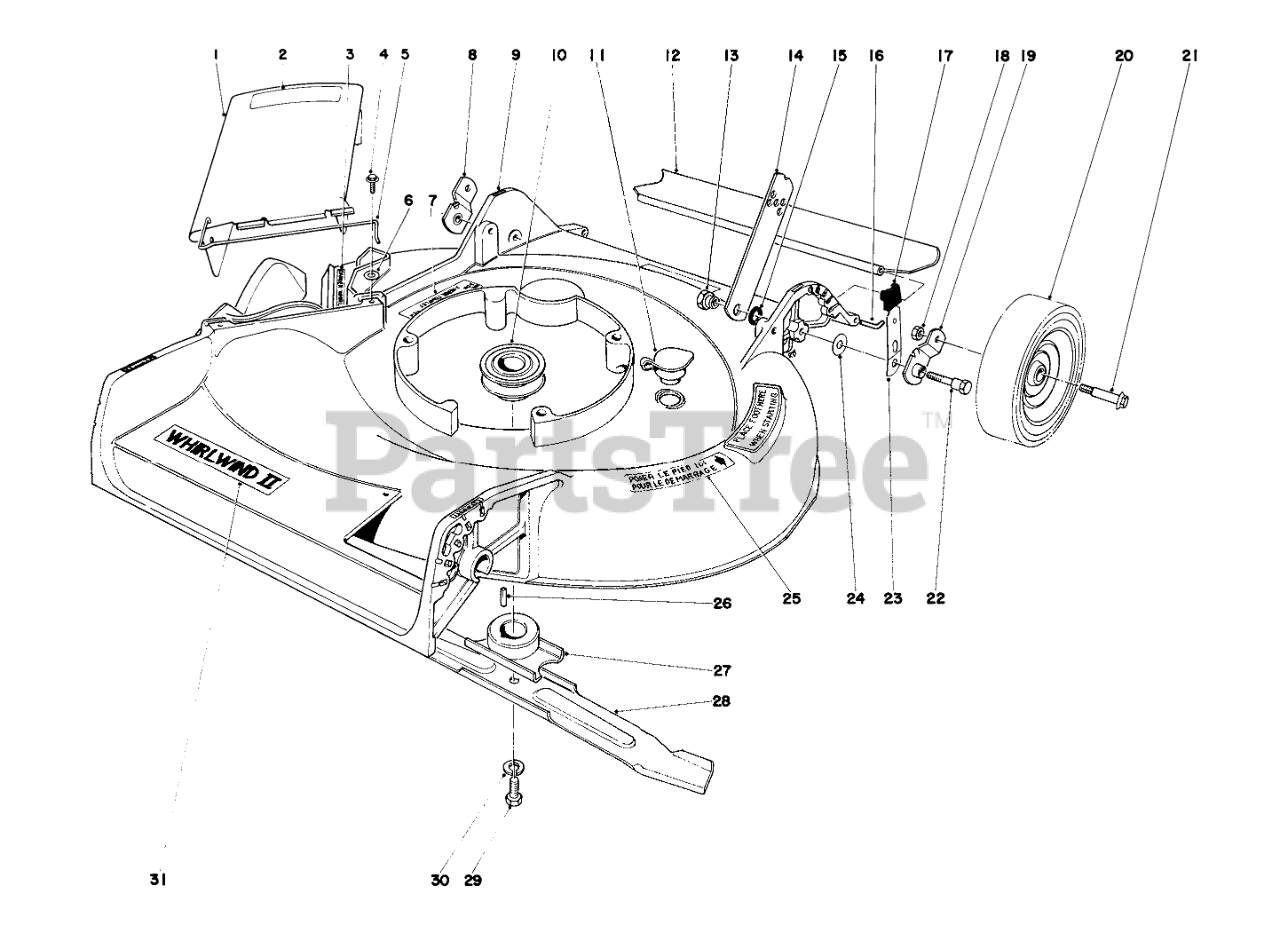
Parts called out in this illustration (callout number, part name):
1	Deflector Cover Assembly (Incl. Ref. #2 & 5)
2	Decal-Caution
3	Decal-Danger
4	SCREW
5	SPRING HINGE
6	WASHER-FLAT
7	Decal-Warning
8	Pivot Arm
9	Housing
10	DRIVER PULLEY
11	WASHOUT PLUG
12	REAR SAFETY SHIELD 21
13	HANDLE PIVOT NUT
14	HANDLE LATCH
15	HANDLE LATCH SPACER
16	SHIELD ROD
17	KNOB-ARM
18	Nut
19	Pivot Arm
20	Wheel Assembly
22	PIVOT SCREW
23	SPRING ARM ASM
24	WASHER-PIVOT
25	Decal-Step
26	KEY-SQUARE
27	Blade Retailer
28	Blade
29	SPECIAL SCREW
30	WASHER-LOCK
31	Decal Whirlwind
